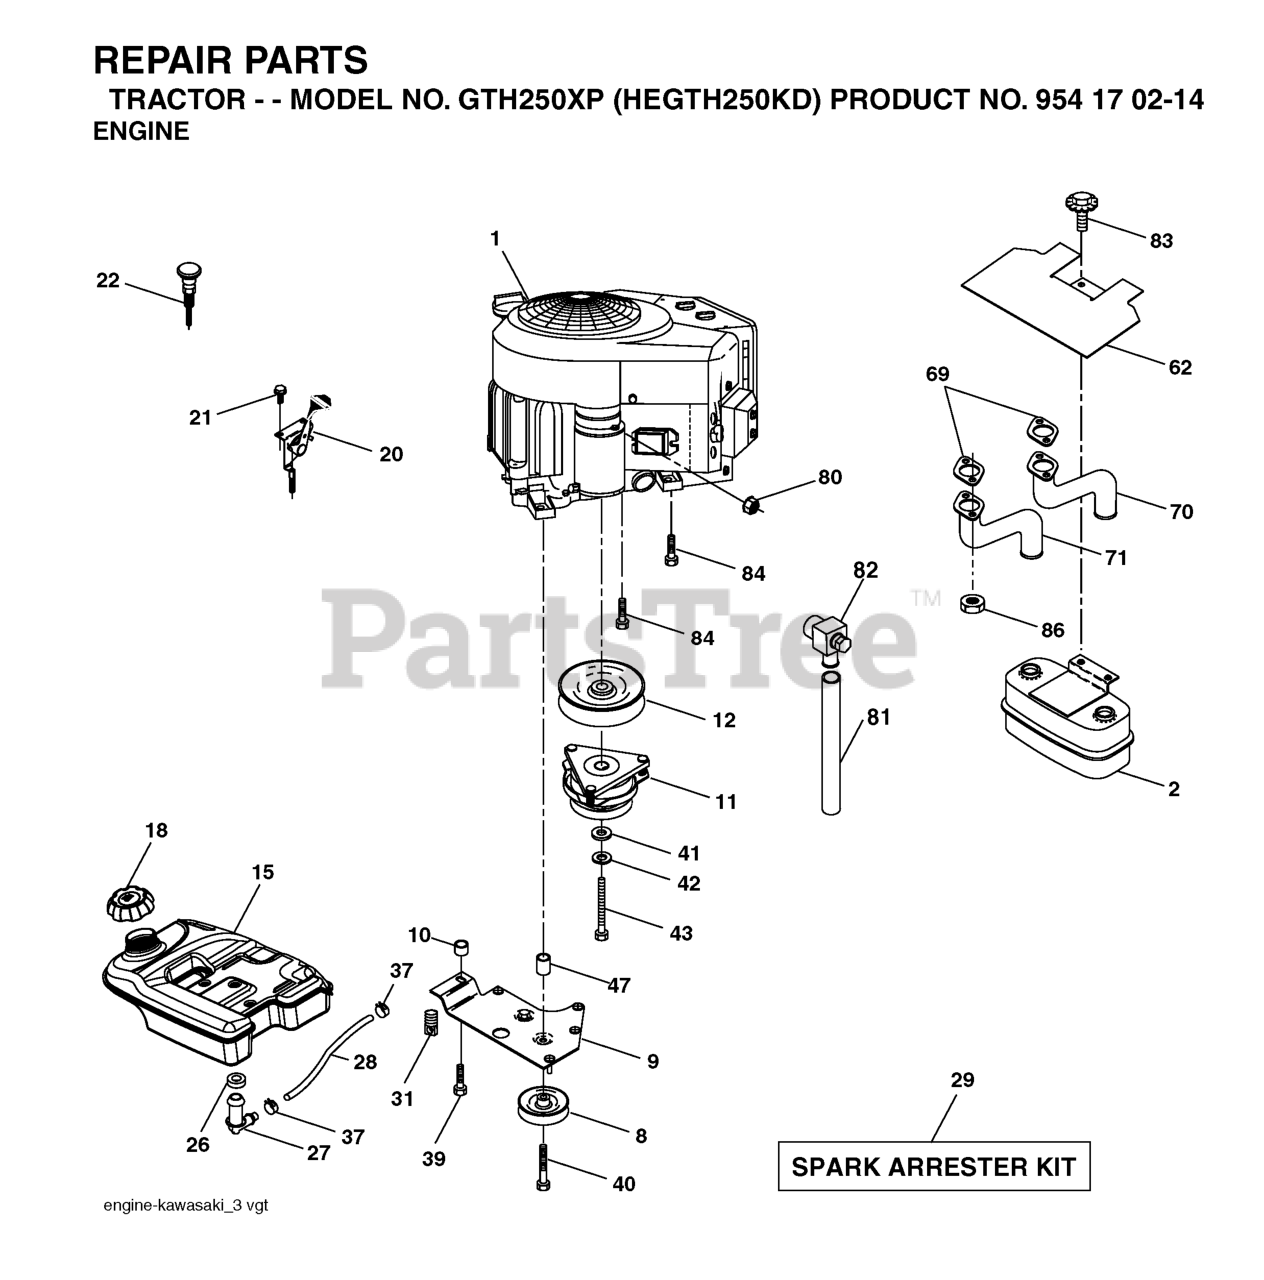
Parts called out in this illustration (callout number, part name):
2	MUFFLER.TWIN.CYL.LOW.TONE
8	RP.IDLER GROOVED
9	KEEPER ASM BELT ENGINE
11	CLUTCH MZ ZTR GT.48/54"1.125"
12	PULLEY ENG VGT ELECT CLUTCH
15	TANK.FUEL.5.0 LEFT.FILL.YTGT
18	TANK CAP
20	CONTROL.THROTTLE.COBRA.42"BLK.
21	SCREW
22	CONTROL, CHOKE
26	BUSHING OUTLET T
27	STEM FUEL TANK
28	HOSE
29	KIT.SPARK ARRESTOR 794945 B&S
37	HOSE CLAMP
39	SCREW TT 3/8-16X2-1/4 UNC
40	Screw TT 3/8-16 x 4 unc
42	LOCKWASHER
43	BOLT HEX 7/16-20 X 3.75 GR. 5
62	HEAT SHIELD
70	TUBE.EXHAUST.KAWASAKI.RH
71	TUBE EXHAUST LH
80	FLANGE NUT
81	TUBE, DRAIN OIL ASM.
83	BOLT.5/16-18UNCX3/4 W/SEMS.BLK
84	SCREW 3/8-16 X 1-1/2
86	NUT.HEX.FLANGE.TOPLOCK
